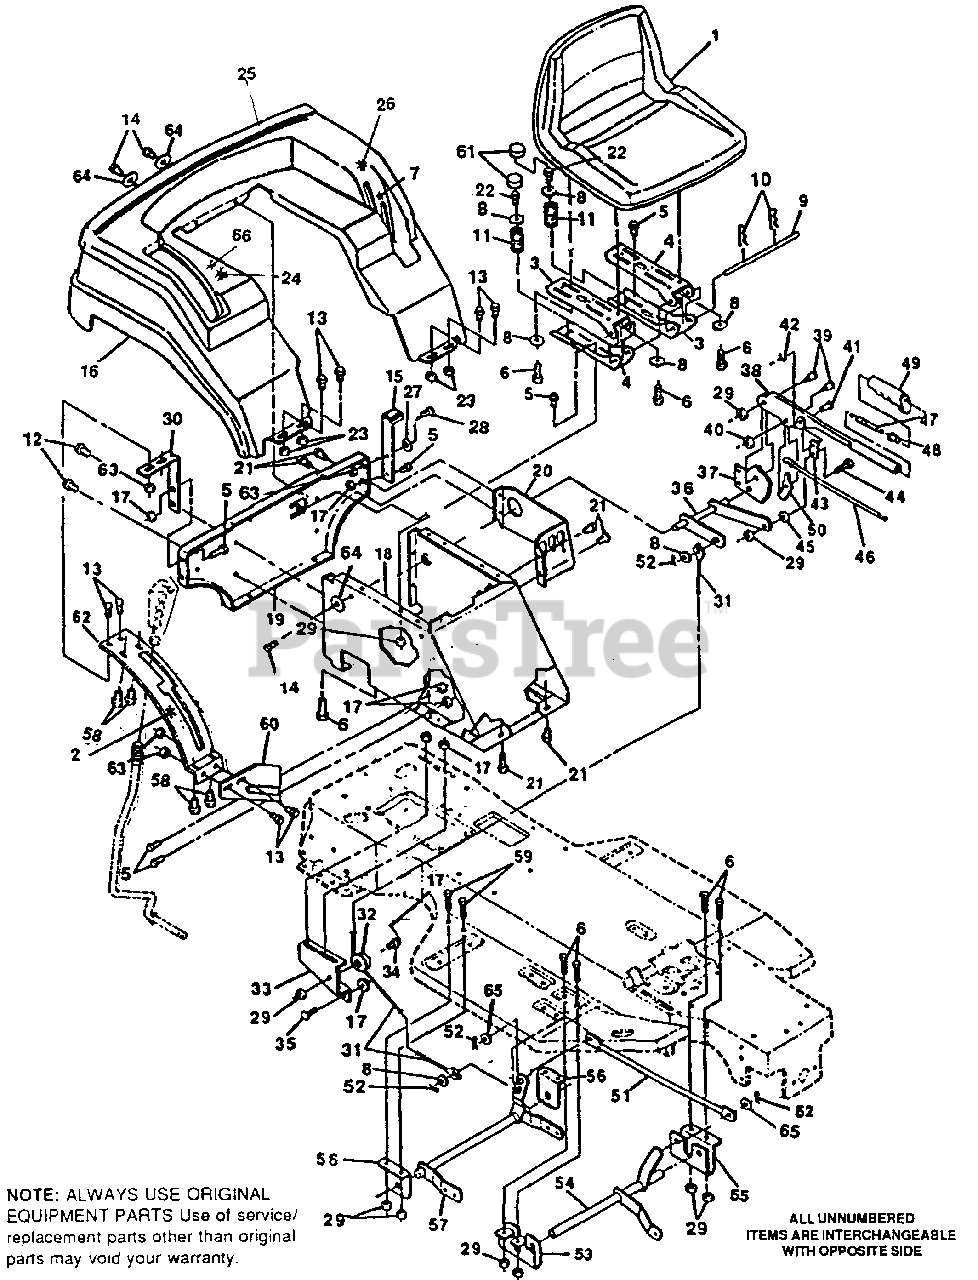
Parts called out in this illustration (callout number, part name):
2	Decal, Hydro
3	Channel, Seat
4	Channel, Seat
5	Screw, Hx Hd, Wd Fl 5/16-18 x 3/4 In.
6	Screw, Hx Hd, 5/16-18 x 3/4 In.
7	Decal, Deck Height
8	Washer, Flat, 11/32 In.
9	Rod, Seat Support
10	Hair Pin, .073 Dia. x 1.13 In.
11	Seat Spring
12	Screw, Tap, 5/16-18 x 7/8 In.
13	Screw, Hx Hd, 1/4-20 x 5/8 In.
14	Screw, Hx, Wsher Hd, Tap 1/4-20 x 5/8 In.
15	Fender Support, L.H.
17	Nut, Hx, Wd Fl, Lk 5/16-18 Thd.
18	Seat Support
19	Support, Fender & Seat
20	Bracket, Support Engage
21	Screw, Hx Wshr Hd Tap, 5/16-18 x 1/2 In.
22	Screw, 5/16-18 x .63
23	Nut, Lock, 1/4-20 Thd.
24	Decal, Patent Pending 4WS
25	Decal, Hydrostatic
26	Decal, Relief Valve Operation
27	Washer, Flat
28	Screw, 1/4-20 x .75
29	Nut, Hx Ctrlk, 5/16-18 Thd.
30	Fender Support, R.H.
31	Cable, Deck Lift
33	Assembly, Pulley Bracket
34	Shoulder Bolt, 5/16-18 Thd.
35	Bolt, Carriage, 5/16-18 x 5/8 In.
36	Assembly, Upper Shaft
37	Quadrant
38	Lift Lever
39	Shoulder Bolt, 5/16-18 Thd.
40	Nut, Hx Wd Fl Lk 5/16-18 Thd.
41	Clevis Pin
44	Shoulder Bolt, 5/16-18 Thd.
46	Actuator Rod
47	Spring, Height Adjust
48	Knob, Height Adjust
49	Handle, Lift
50	Pawl, Height Adjust
52	Cotter Pin
53	Bracket, L.H. Front Hanger
54	Assembly, Front Lift Shaft
55	Bracket, R.H. Front Hanger
56	Bracket, Hanger
57	Assembly, Rear Lift Shaft
58	Screw, Hx Hd, Tap # 10 x 1/2 In.
59	Screw, Hx Hd, 5/16-18 x 5/8 In.
60	Support, Shift Plate
61	Cover, Seat Spring
62	Quadrant
63	Nut, Hx, Wd Fl Lk, 1/4-20 Thd.
64	Washer, Flat, .281 x 1.00 x .063
65	Washer, Flat, 13/32 In.
66	Decal, Husqvarna U.S.A 4140H
